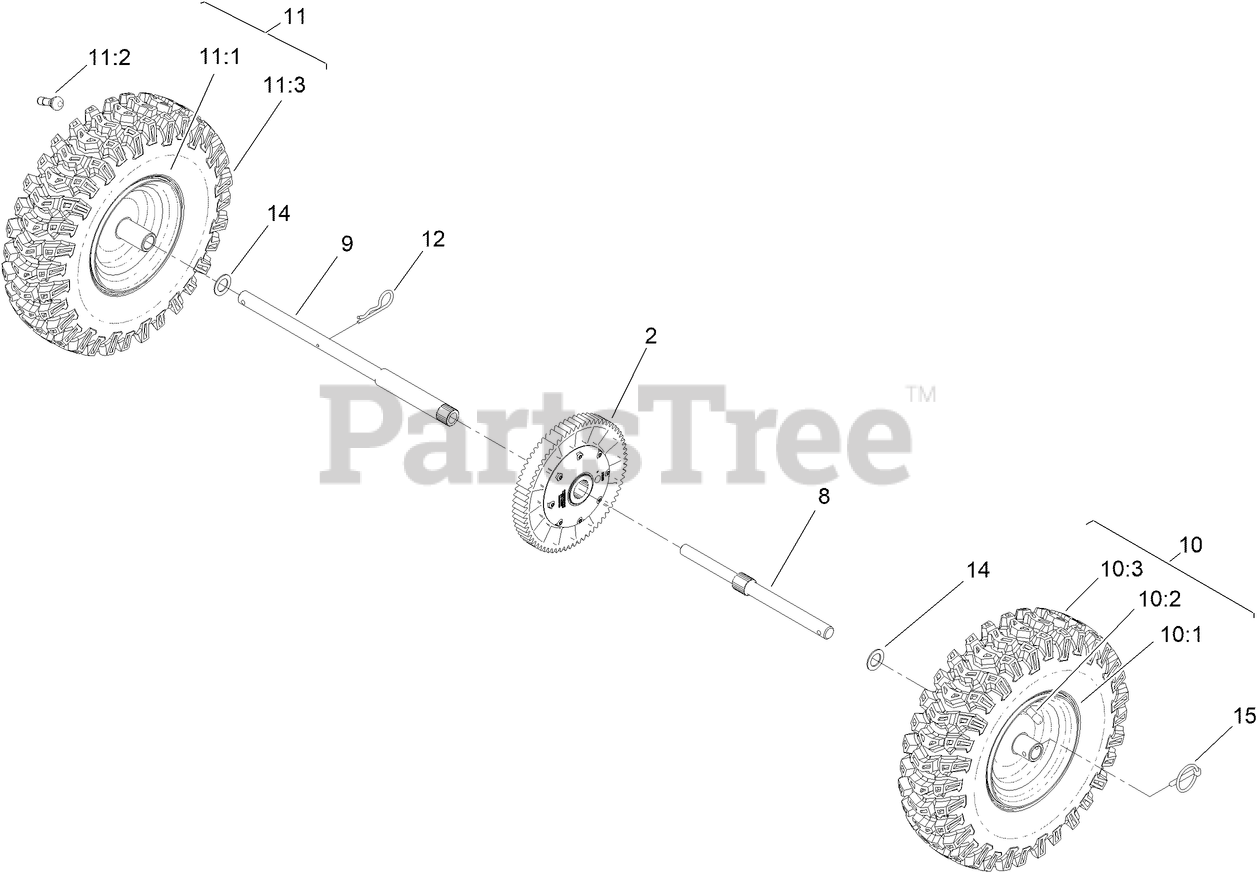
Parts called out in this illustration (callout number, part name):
2	TRANSMISSION-GT, DI200
8	AXLE-LT, CTS
9	AXLE-RT, CTS
10	LH WHEEL AND TIRE ASM
10:1	WHEEL (15X4 TIRE)
11	RH WHEEL AND TIRE ASM
11:1	WHEEL (15X4 TIRE)
12	PIN-HAIR
14	WASHER-THRUST
15	KLIK PIN ASM
